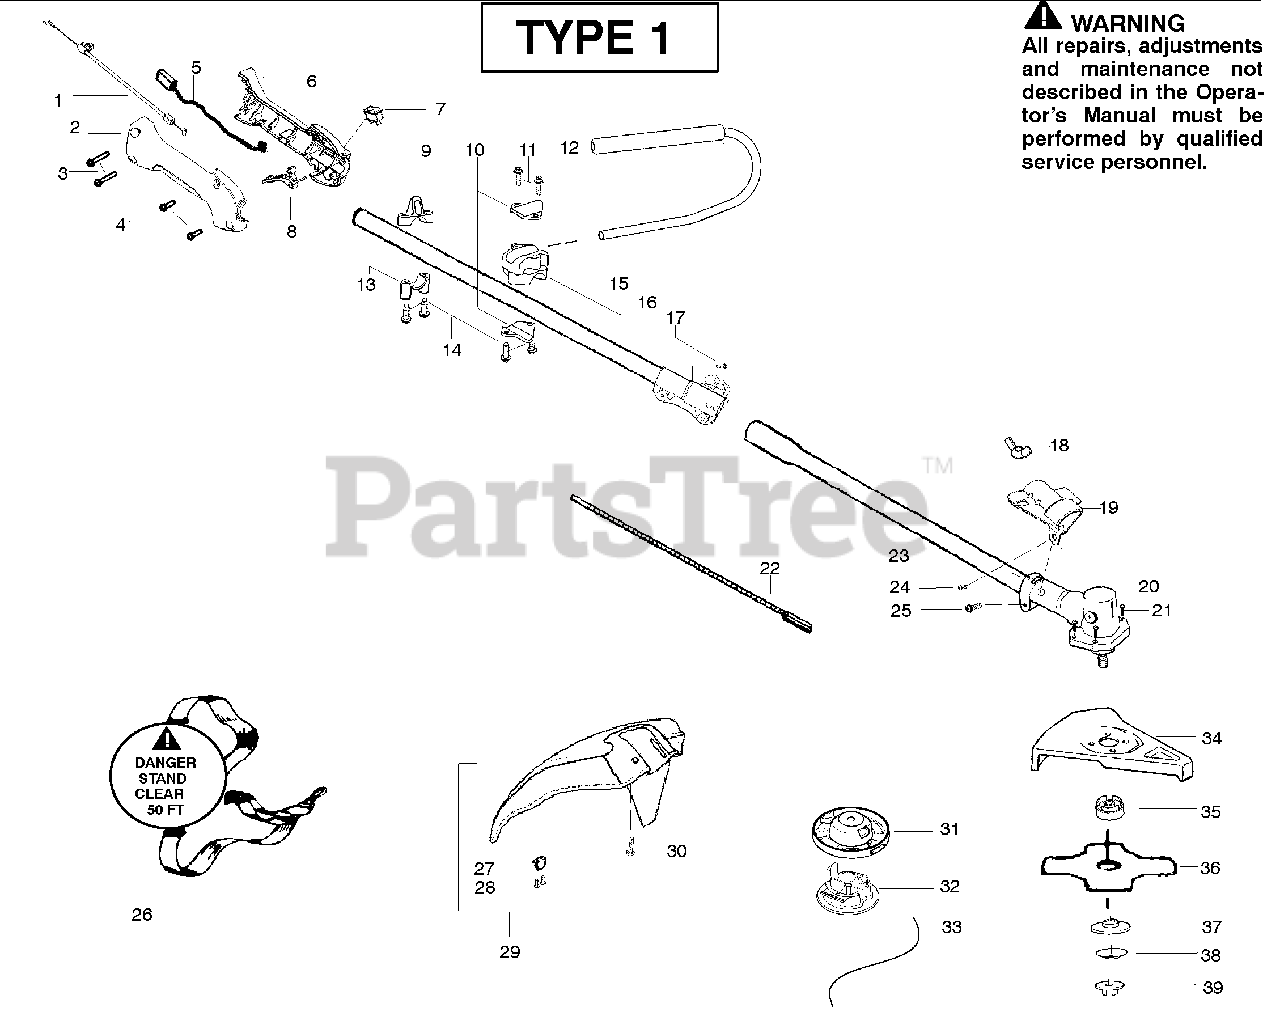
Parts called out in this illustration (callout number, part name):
1	Assy-Throttle Cable
2	Hsg-Throttle-right
6	Hsg-Throttle-left
8	Trigger-Throttle
9	Clamp-Harness (upper)
10	Clamp-Bracket
12	Assy-Handlebar
13	Clamp-Harness (lower)
15	Clamp-Handlebar
16	Kit-Upper Shaft
18	Wingnut
19	Bracket-Shield
22	Shaft-Flex (lower)
23	Assy-Lower Shaft
26	Shoulder Strap
29	Kit-Shield Assy
31	Head-Fixed line
32	Cap-Fixed Line
33	Accy-Line (12 pcs)
34	Kit-Metal Shield
36	Accy-Weed Blade
38	Washer-Belleville
